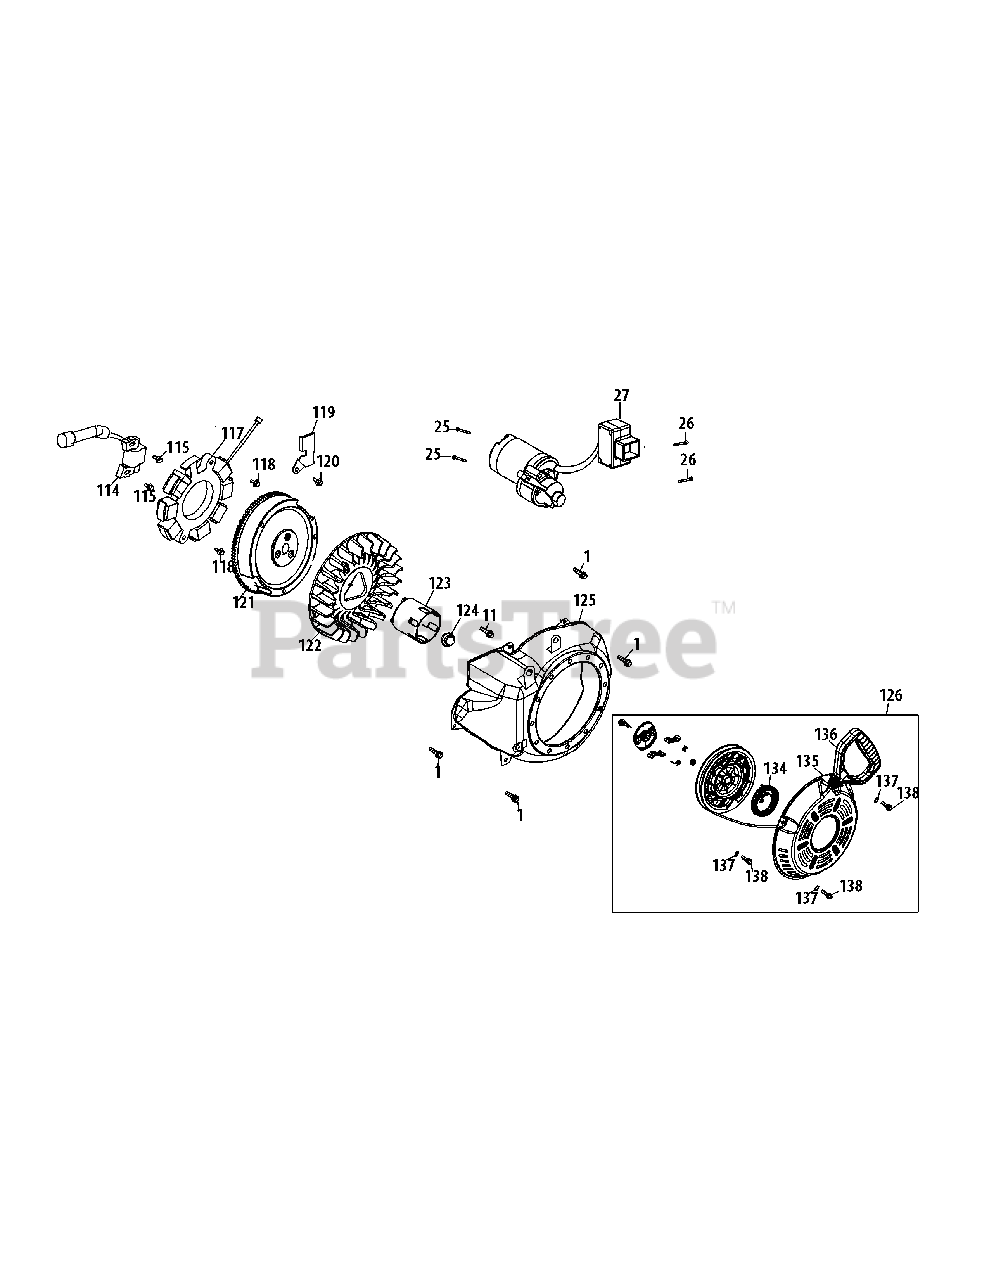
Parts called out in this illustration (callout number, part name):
1	BOLT M6×12
11	BOLT M6×16
25	BOLT M8×55
26	BOLT M4×55
27	ELECTRIC STARTER
114	IGNITION COIL ASSEMBLY
115	IGNITION COIL BOLT
117	ALTERNATOR ASSEMBLY
118	BOLT M6×30
119	WIRE PLATE
120	BOLT M6×8
121	FLYWHEEL
122	COOLING FAN
123	STARTER CUP
124	NUT M16×1.5
125	BLOWER HOUSING
126	RECOIL STARTER
134	RECOIL SPRING
135	BLOWER HOUSING
136	STARTER HANDLE
137	GASKET 06
138	BOLT M6×10
